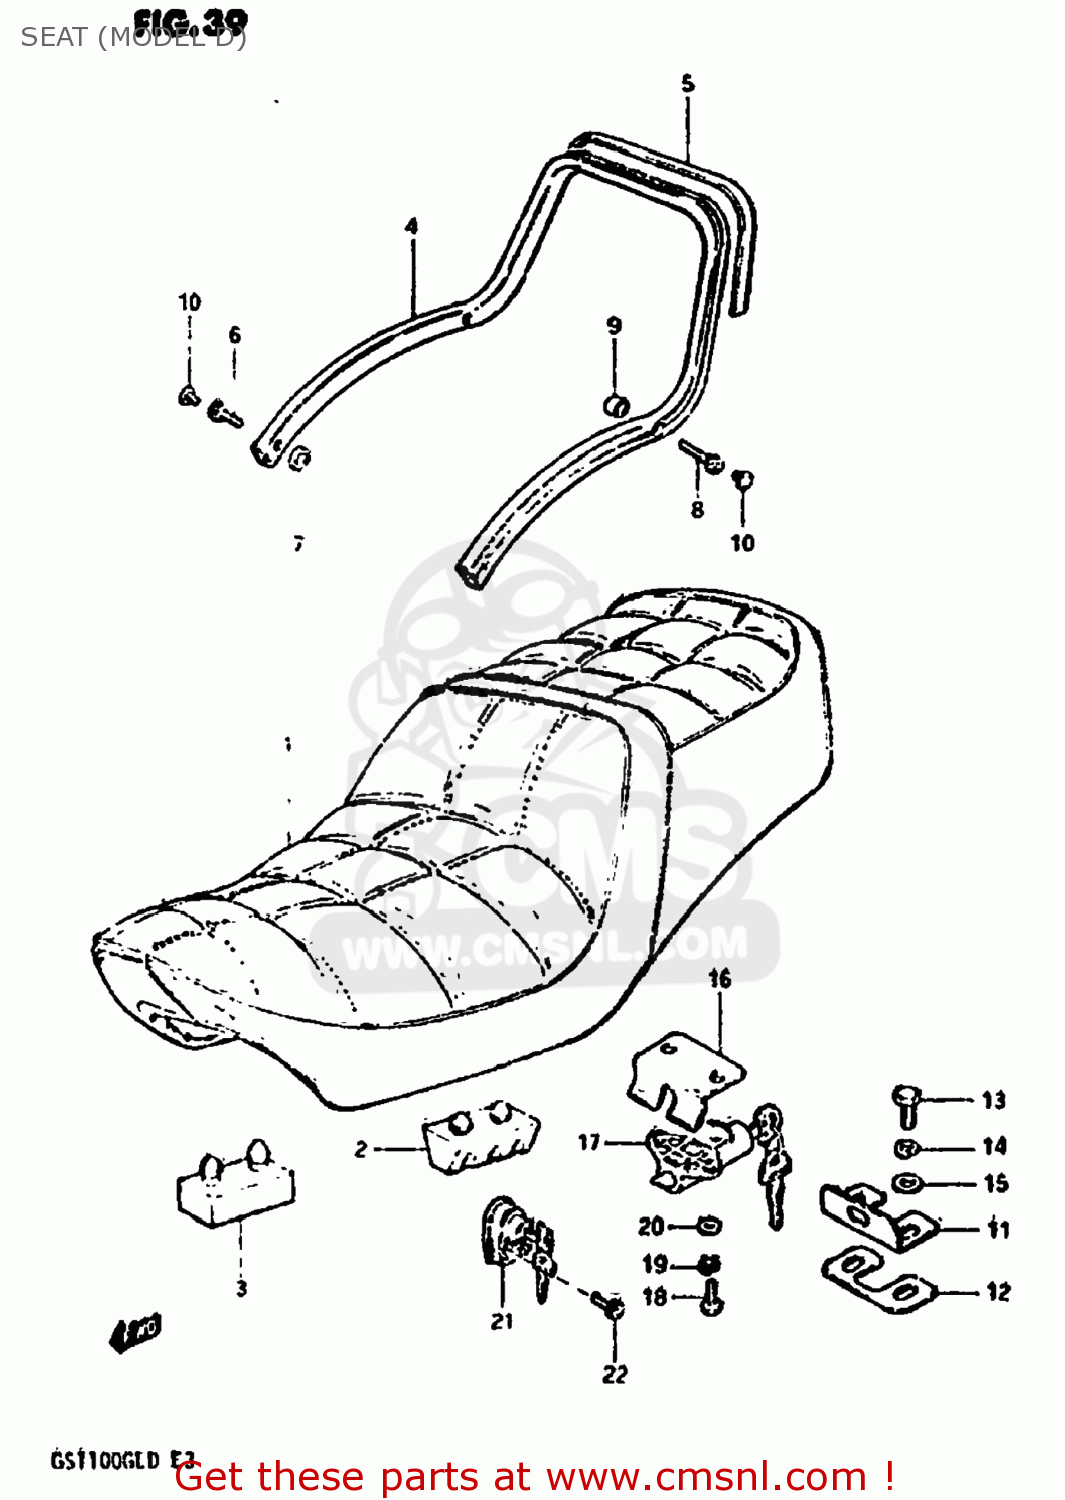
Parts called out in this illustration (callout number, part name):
1	SEAT ASSEMBLY
2	CUSHION,SUPPORT(50X25X32)
3	CUSHION
4	HANDLE,PILLION RIDER
5	RUBBER,PILLION RIDER HANDLE
6	BOLT
7	SPACER,REAR
8	BOLT
9	SPACER,REAR
10	CAP(OD:14.5)
11	STRIKER,SEAT LOCK
12	SHIM,SEAT LOCK STRIKER
13	BOLT, UPPER
14	LOCK WASHER
15	WASHER
16	PLATE,SEAT LOCK
17	LOCK ASSEMBLY,SEAT
18	BOLT
19	LOCK WASHER
20	WASHER 6MM
21	LOCK ASSY,HELMET
22	BOLT 5X25
